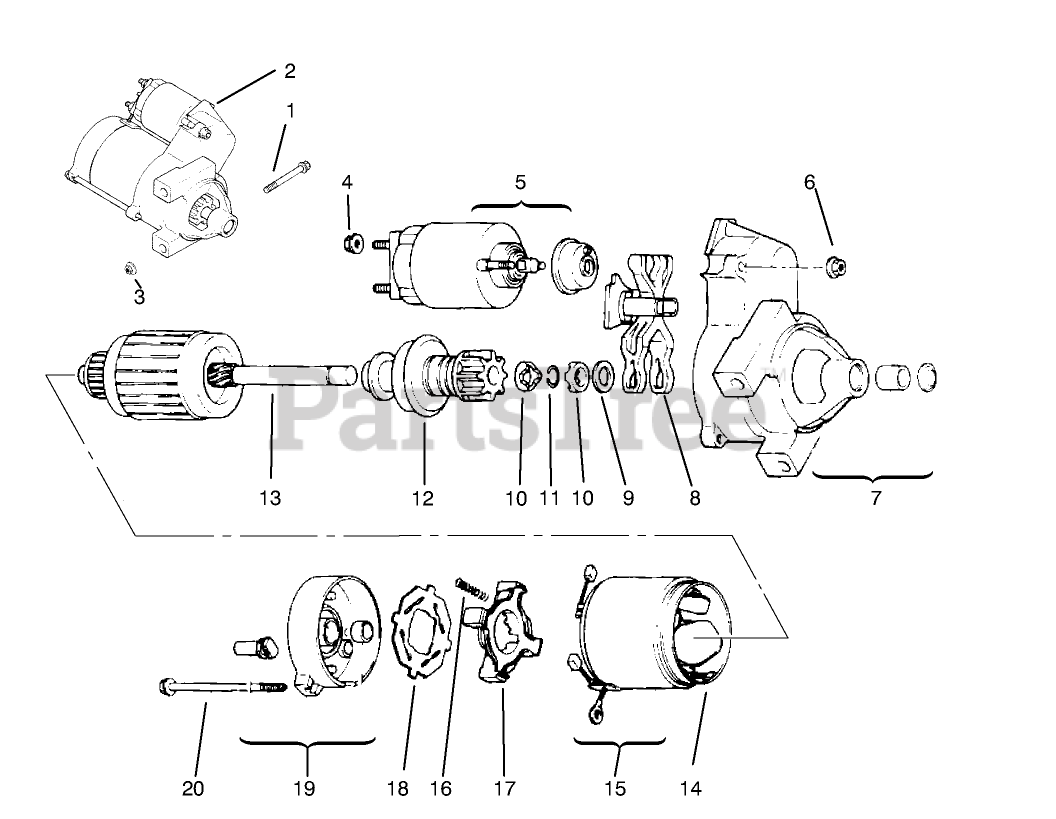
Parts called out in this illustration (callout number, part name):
1	Screw M8x1.25x80 (Only On: 72103, 72083)
2	Starter-Solenoid Shift (Incl. Ref. # 4-20)
4	Nut
5	Solenoid
6	Nut Starter
7	Cap-Drive End
8	Lever Starter Drive
9	Washer-Thrust (Only On: 72103, 72083)
10	Nut-Stop Collar
11	Ring-Retainer
12	Drive-Pinion
13	Armature-Starter
14	Frame
15	Kit-Brush (Incl. Ref. # 16)
16	Spring-Brush
17	Holder-Brush
18	Insulator
19	Cap-Commutator End
20	Bolt
